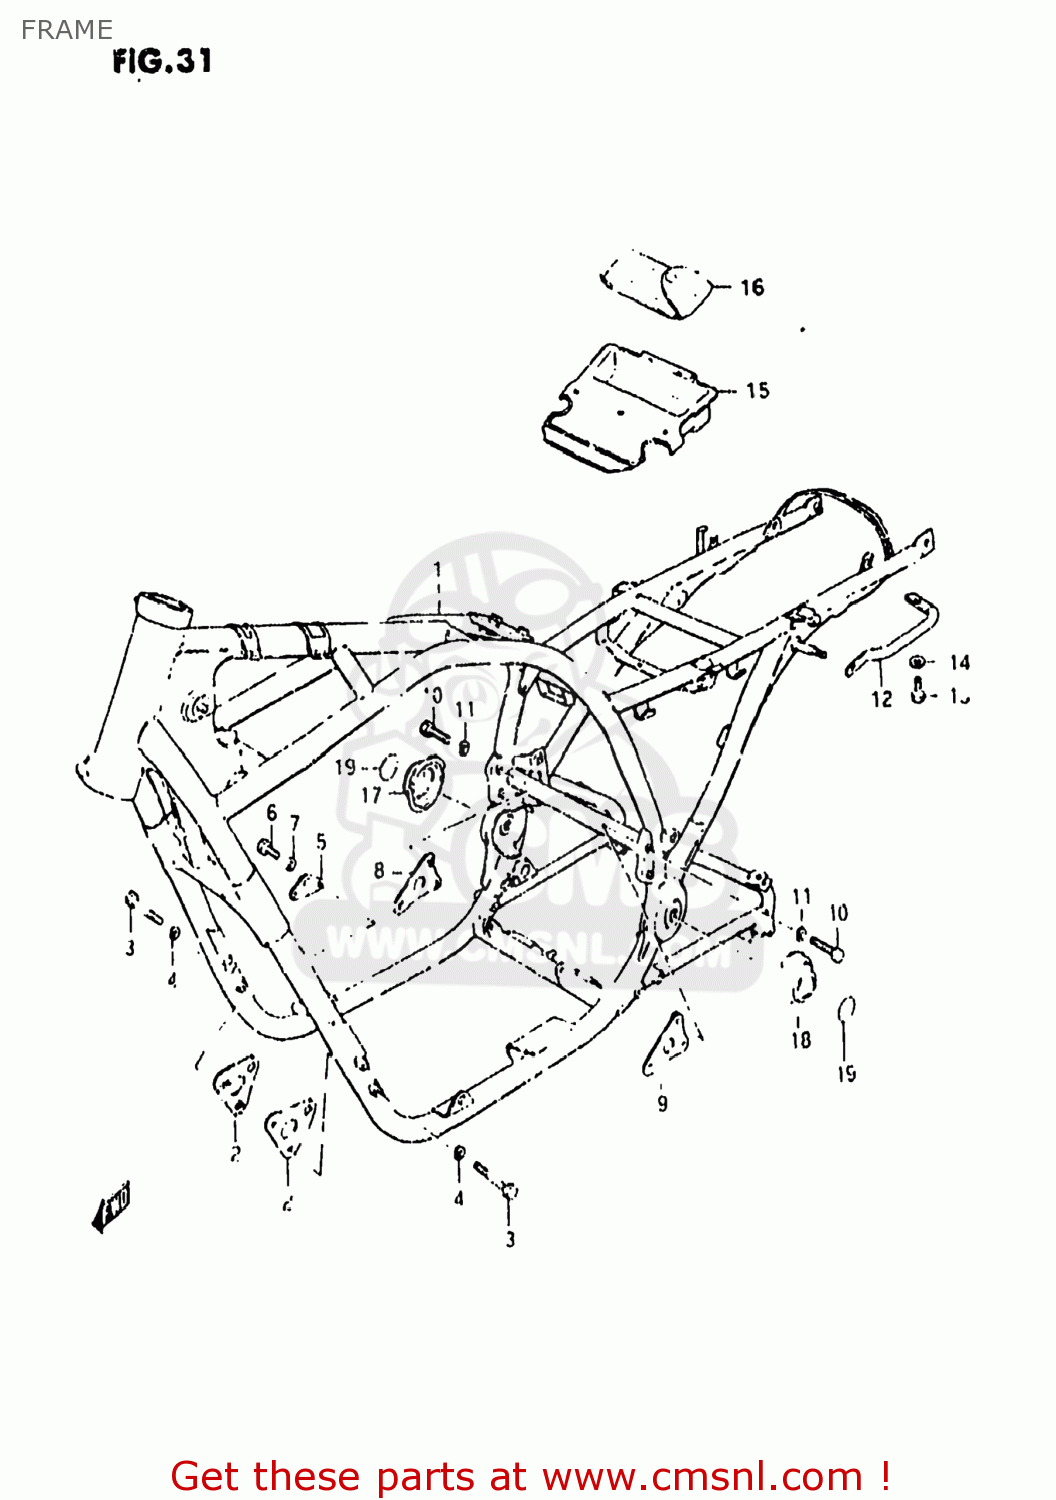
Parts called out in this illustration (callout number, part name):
1	FRAME
2	PLATE,ENGINE MOUNTING
3	BOLT
4	LOCK WASHER
5	PLATE,ENGINE MOUNTING
6	BOLT
7	LOCK WASHER
8	PLATE,ENGINE MOUNTING
9	PLATE,ENGINE MOUNTING
10	BOLT 8X40
11	LOCK WASHER
12	GRIP,FRAME
13	BOLT
14	WASHER
15	HOLDER,TOOL
16	TOOL SET
17	COVER,REAR SWING ARM PIVOT
18	COVER,REAR SWING ARM PIVOT
19	TAPE,REAR SWING ARM PIVOT
